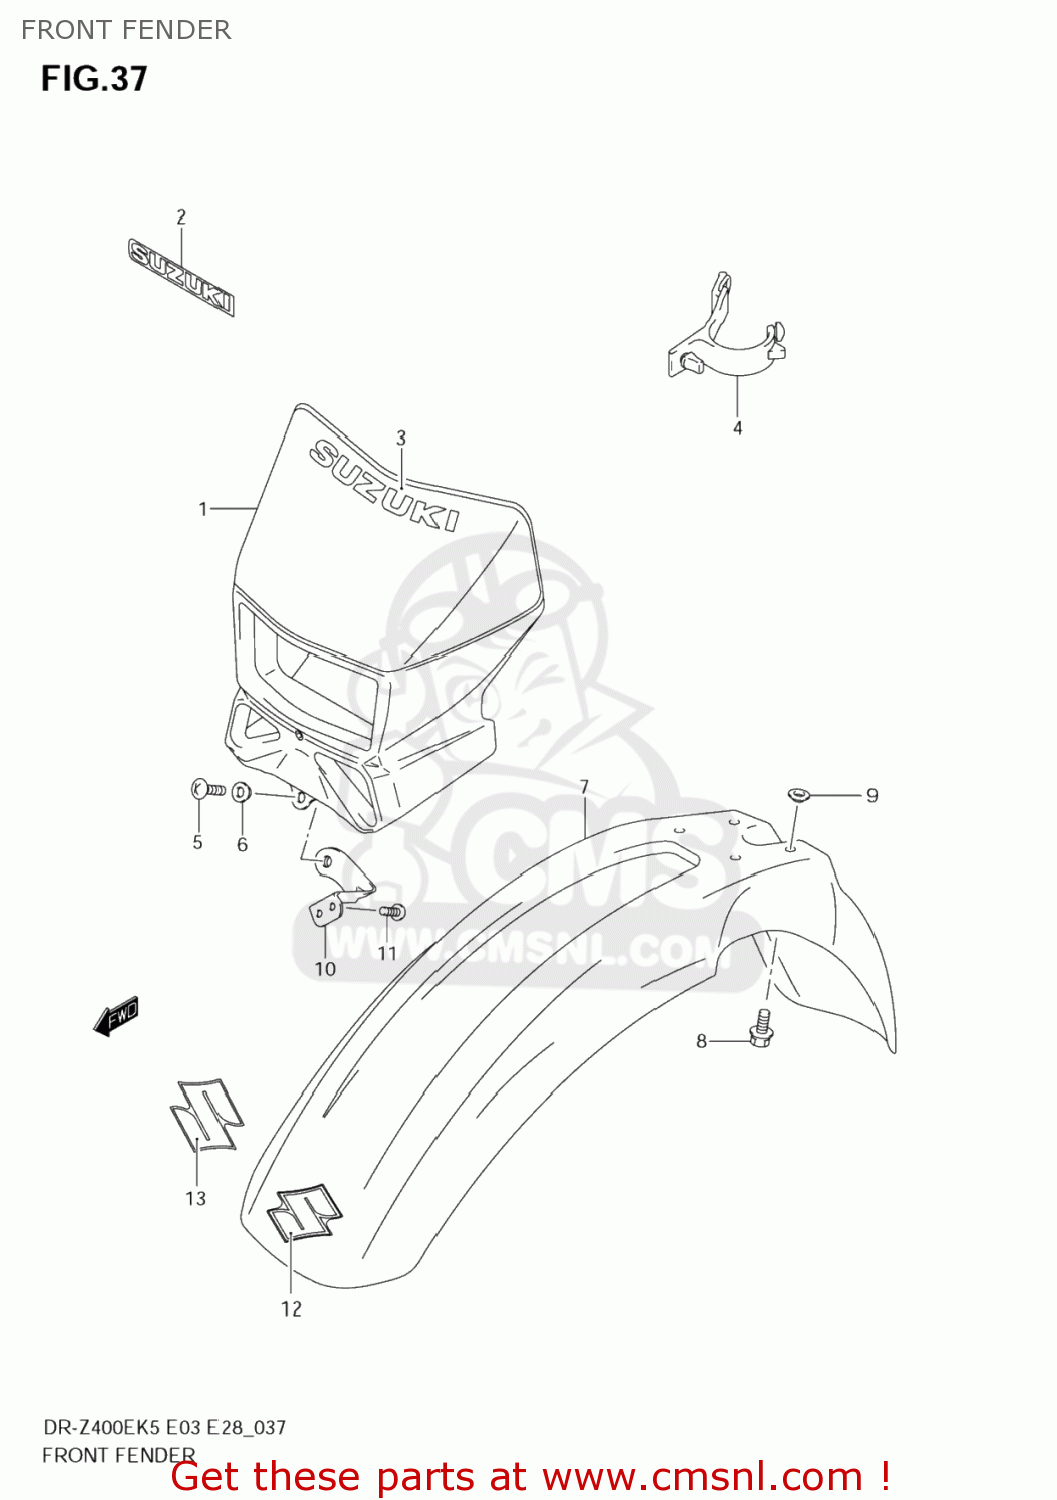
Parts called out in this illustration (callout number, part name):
1	COVER,HEADLAMP
2	EMBLEM,SUZUKI
3	TAPE,HEADLAMP HOUSING
4	BAND,HEADLAMP COVER
5	SCREW(5X12)
6	WASHER
7	FENDER,FR
8	BOLT(6X16)
9	WASHER
10	BRACKET,HEADLAMP COVER
11	SCREW(6X16)
12	EMBLEM,S
13	EMBLEM,S
